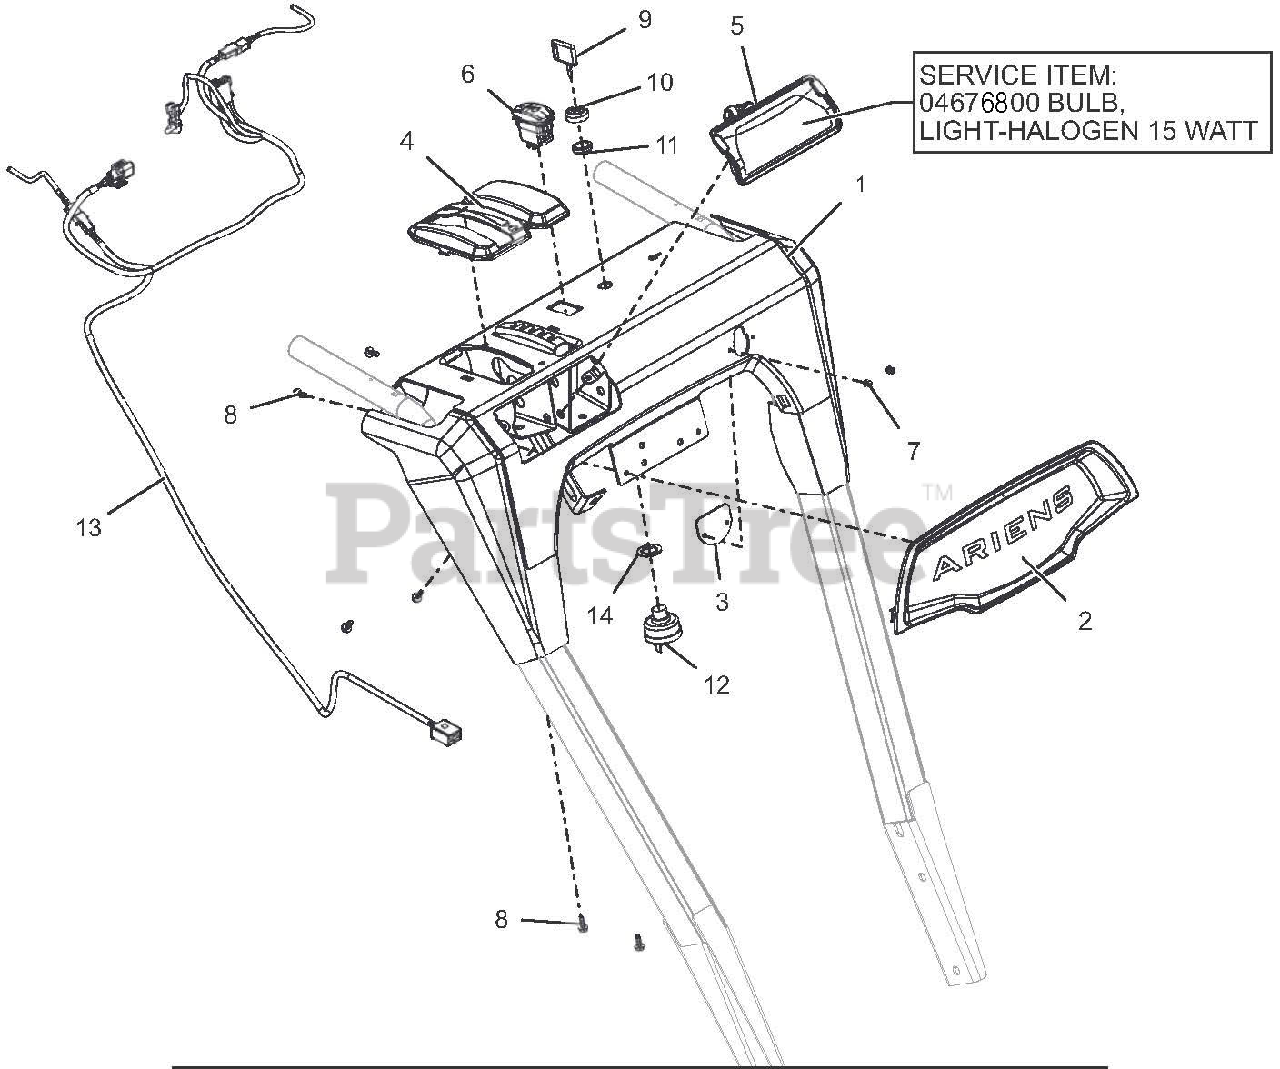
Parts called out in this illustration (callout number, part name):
1	PANEL, DASH - W/CTR DECAL(12V)
2	BEZEL, DASH - ARIENS LG DASH
3	COVER, DASH BRKT, BRUSH
4	BEZEL, SHIFT - HYDRO BRUSH
5	HEADLIGHT ASY, HOLO 15W 2 SHOT
5	BULB, LIGHT-HALOGEN 15 WATT
6	SWITCH,ROCKER SPST-ON/OFF
7	RVT-POP #43 .125X.313 STL ZINC
8	SCR-TAP #10X.50 BOSS INDHXHD
9	KEY -W/CAP
10	CAP - IGNITION SWITCH
11	NUT-PANEL .625-32 GRECO
12	IGNITION SWITCH ASSEMBLY
13	HARNESS,ELEC - HANDLEBAR 12V
14	WSHR-LK-INT .625X.045 YWZC
